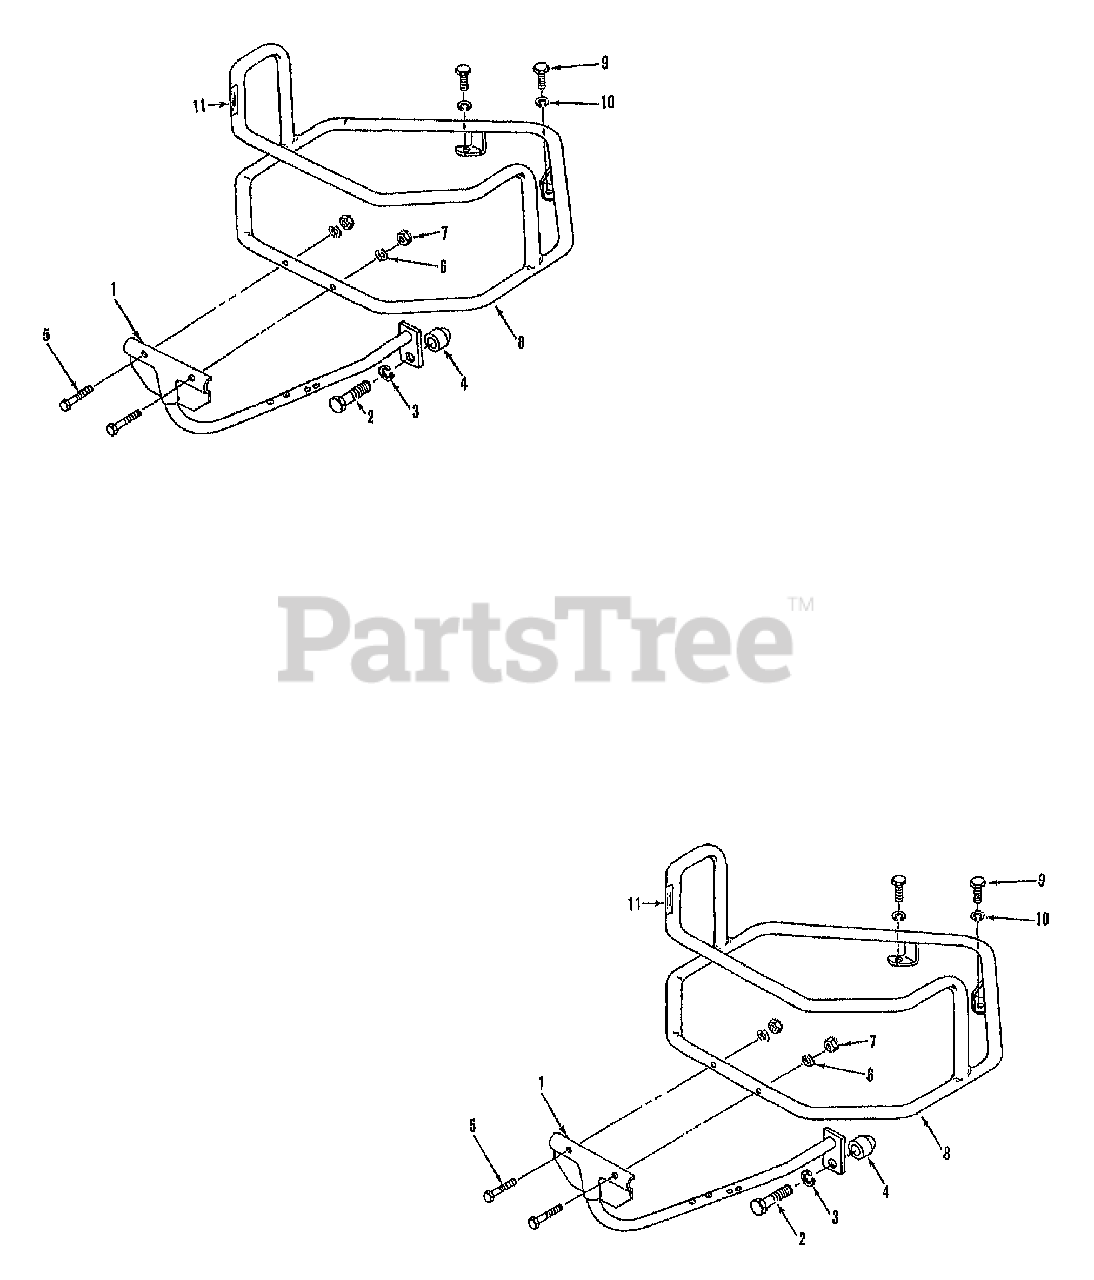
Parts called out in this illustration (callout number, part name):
1	BRACE-BUMPER BOTTOM PNT
2	SCR-HH 1/2-13X2.0 G5 ZP
3	WASHER-LK .5
4	SPACER-1X.531X1.125 ZP
5	SCR-HH 5/16-18X1.5 G5 ZP
6	WASHER-LK .312 ZP
7	NUT-HEX 5/16-18 ZP
8	GUARD-BUMPER HORSE RED
9	SCR-HH 3/8-16X1.0 G5 ZP
10	WASHER-LK .375 @ DEPL
11	DECAL-BUMPER
